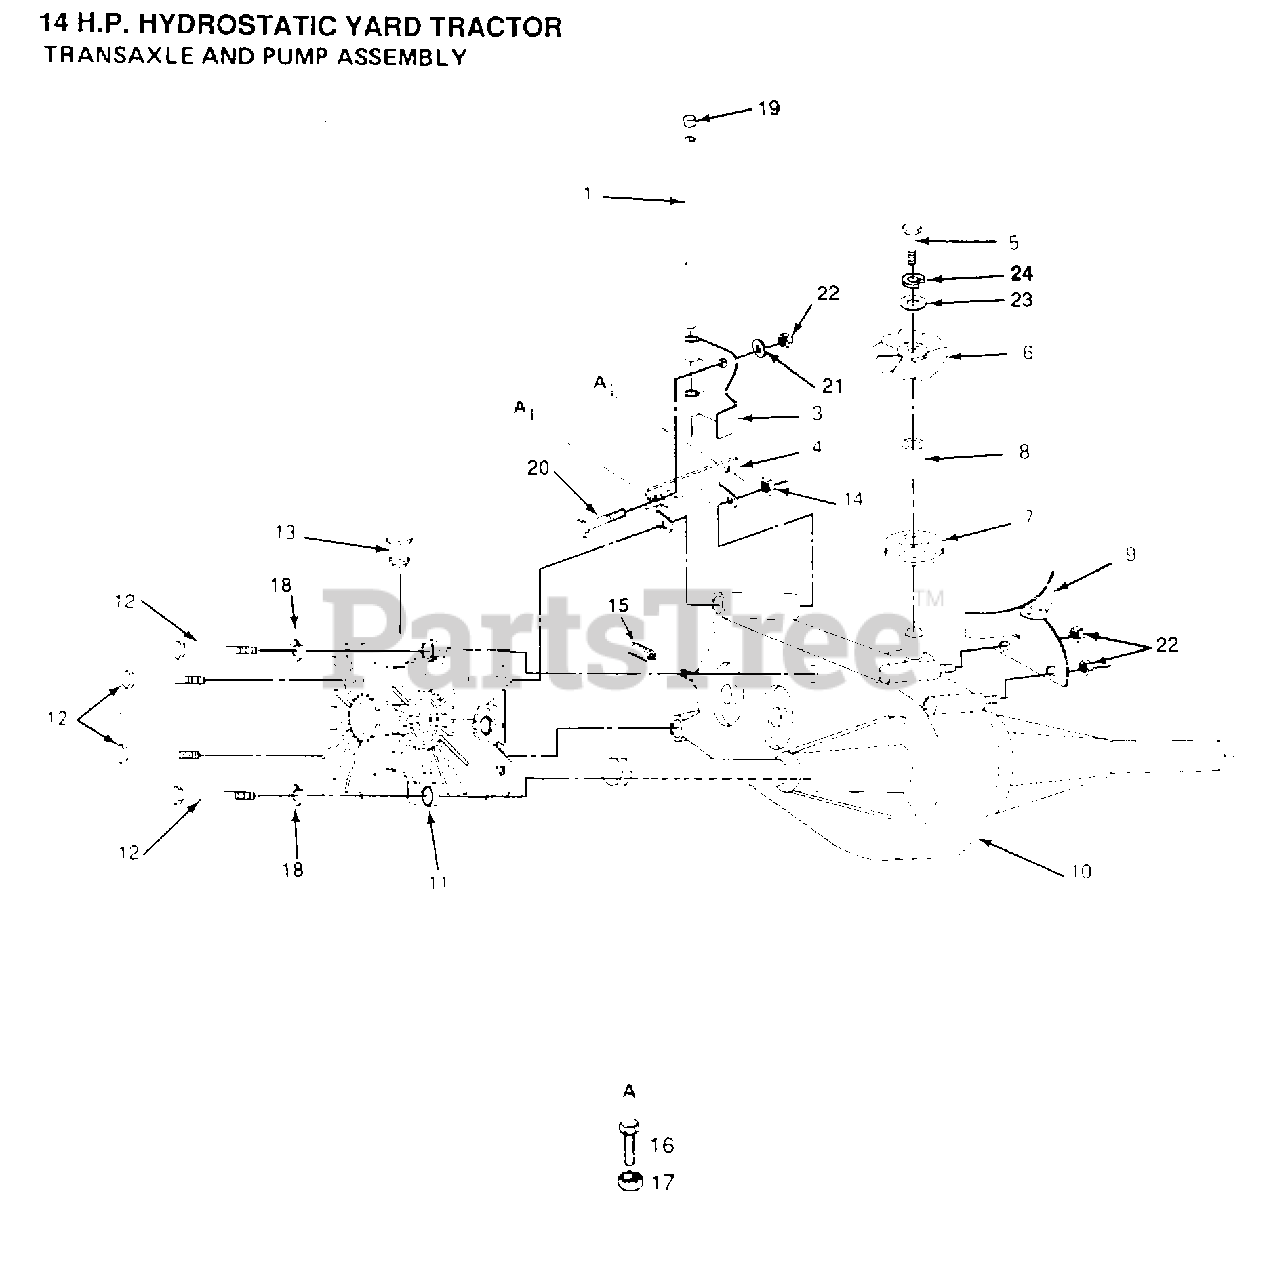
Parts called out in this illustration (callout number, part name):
4	BRACKET
6	FAN
7	PULLEY TRANSAXLE
8	STANDOFF
9	GUARD ASSY
12	BOLT
13	PUMP.2003081.
15	SPRING
18	LOCKWASHER
19	PLUNGER CAP T
20	BOLT T
21	WASHER T
23	WASHER
24	LOCKWASHER
